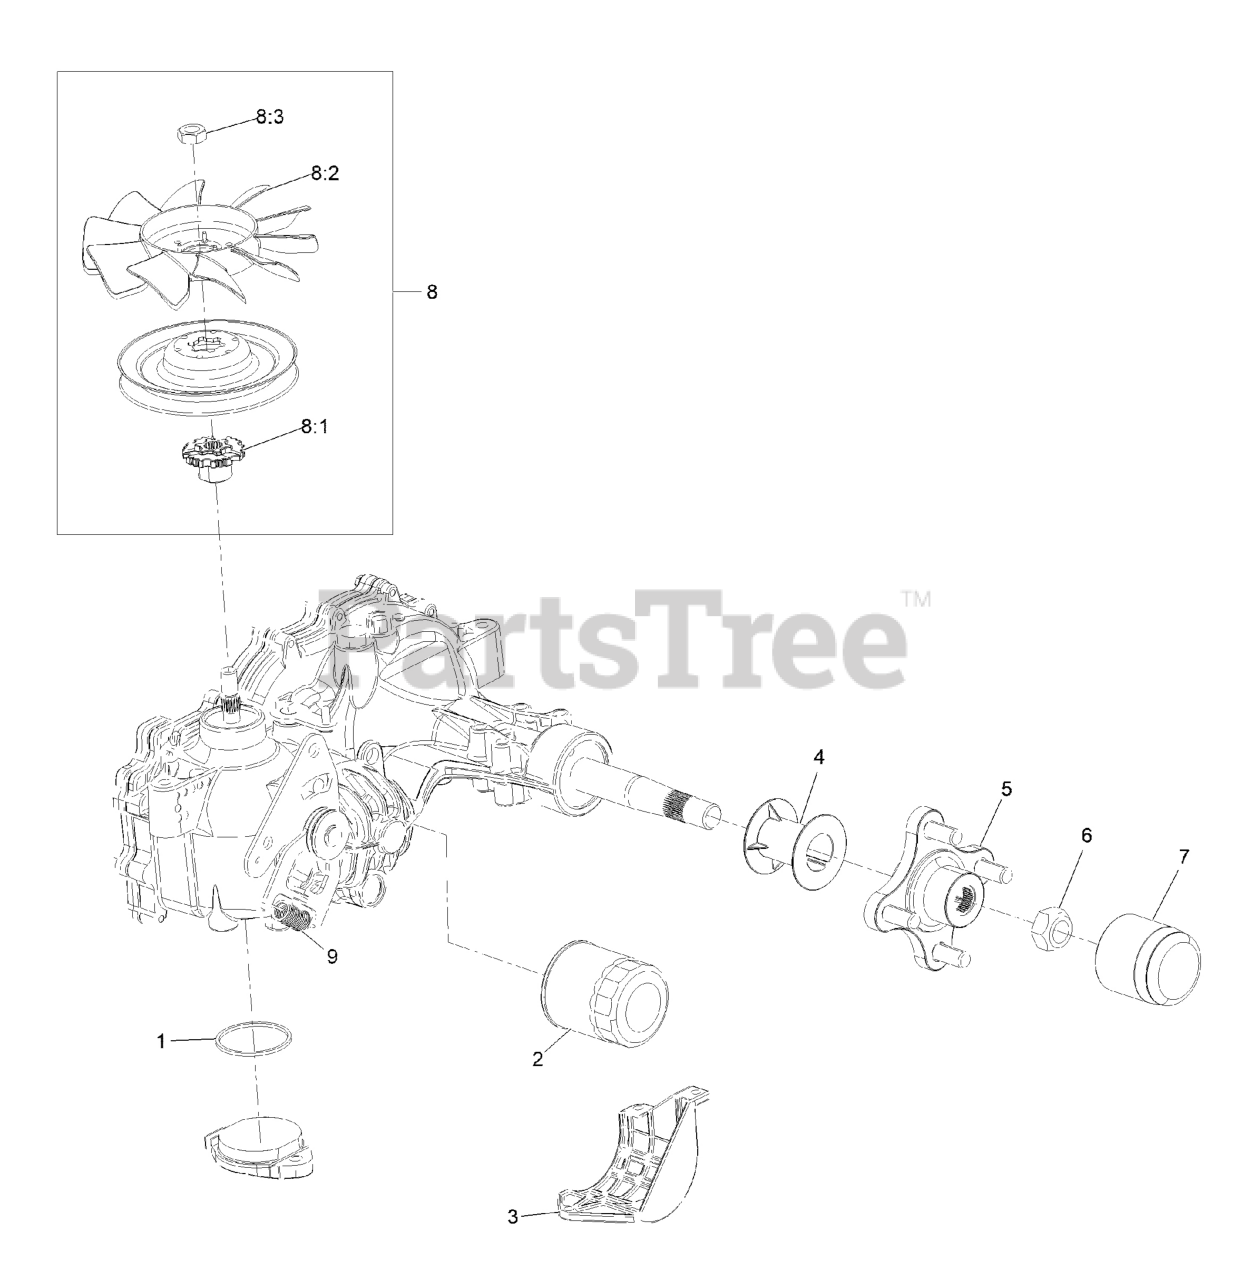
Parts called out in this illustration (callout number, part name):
1	O RING-SEAL
2	ELEMENT-OIL FILTER, HYD
3	GUARD-FILTER, LH
4	TUBE-AXLE
5	HUB-OFFSET
6	NUT-HUB
7	CAP-AXLE, LONG
8	FAN AND PULLEY KIT
8:1	HUB-FAN
9	SPRING-EXTENSION
